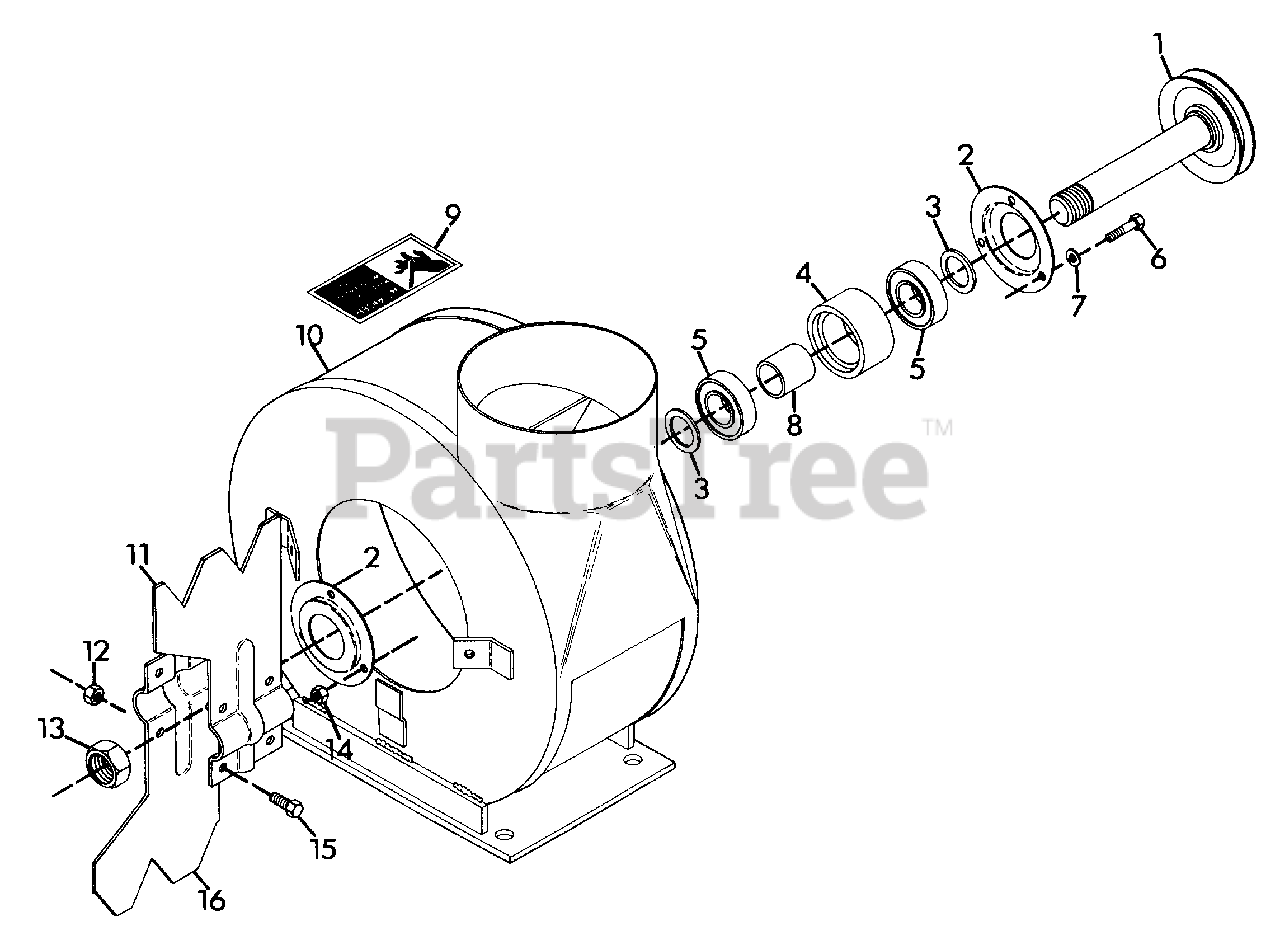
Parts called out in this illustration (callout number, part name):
1	WELDMENT, SPINDLE
2	BEARING, FLANGE
3	WASHER, 1.000/1.031X1.500X.125
4	HOUSING
5	BEARING, BALL
6	BOLT, HEX 1/4-20X2.00
7	WASHER, .263/.273X.562X.046
8	SPACER
9	DECAL, DANGER HAND
10	HOUSING, FAN
11	BLADE, FAN
12	NUT, LOCK 5/16-18
13	NUT, HEX 1-14 JAM LOCK
14	NUT, LOCK 1/4-20
15	BOLT, HEX 5/16-18X.625
16	BLADE, FAN
